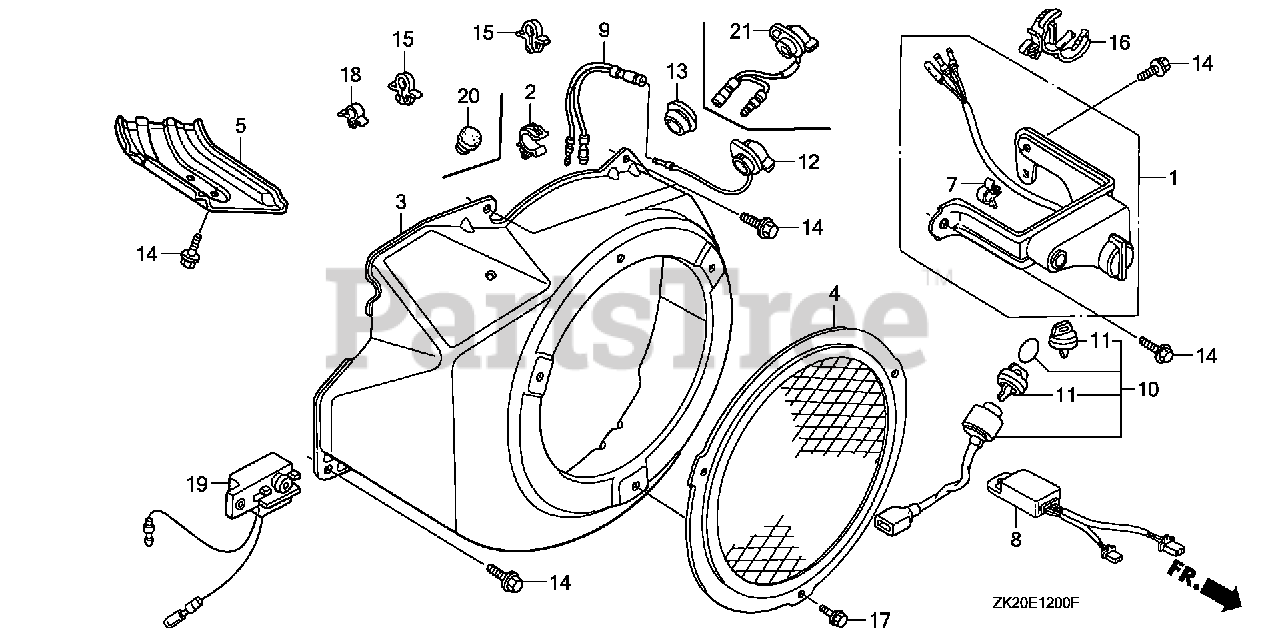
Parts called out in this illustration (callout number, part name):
3	COVER, FAN *R280* (POWER RED)
12	SWITCH ASSY., ENGINE STOP
14	BOLT, FLANGE (6X12) (CT200)
20	PLUG, HOLE
